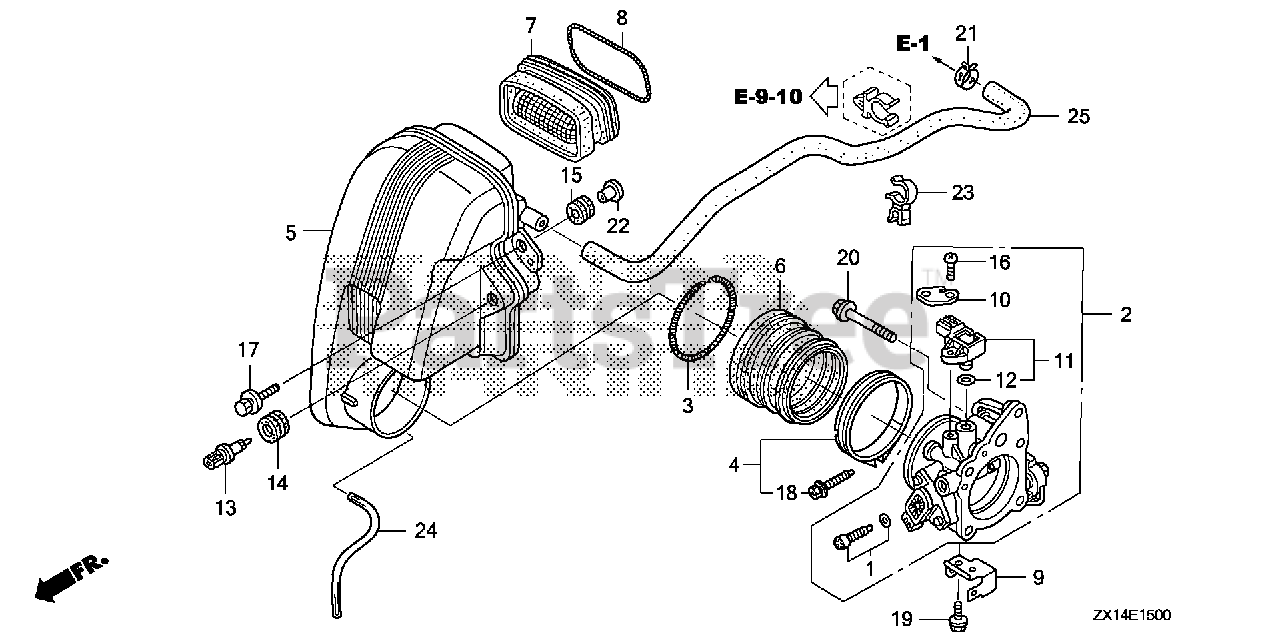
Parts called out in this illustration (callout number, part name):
2	BODY ASSY., THROTTLE
3	SPRING, AIR FLOW TUBE
4	BAND, AIR FLOW
5	CASE, MUFFLER
6	GROMMET, MUFFLER
7	GROMMET, MUFFLER DUCT
8	SPRING, MUFFLER DUCT GROMMET
9	BRACKET E, HARNESS CLIP
10	BRACKET, SENSOR WIRE
11	SENSOR ASSY., MAP
13	SENSOR ASSY., AIR TEMPERATURE (MATSUSHITA DENSHI)
14	GROMMET, TA SENSOR
15	GROMMET, CASE (LOWER)
16	SCREW, PAN (5X18)
17	BOLT-WASHER (6X25)
18	BOLT-WASHER (5X30)
19	BOLT, FLANGE (6X12)
20	BOLT, FLANGE (8X60)
21	CLAMP, TUBE (D17)
22	COLLAR, MODULE IGNITION CONTROL CASE (CDI)
23	CLAMP, FUEL HOSE
24	BULK HOSE, VINYL (4X7X8000) (95003-07(95003-07001-60M) (CARBURETOR NO.)
25	BULK HOSE, VACUUM (12X1000) (12X740)
